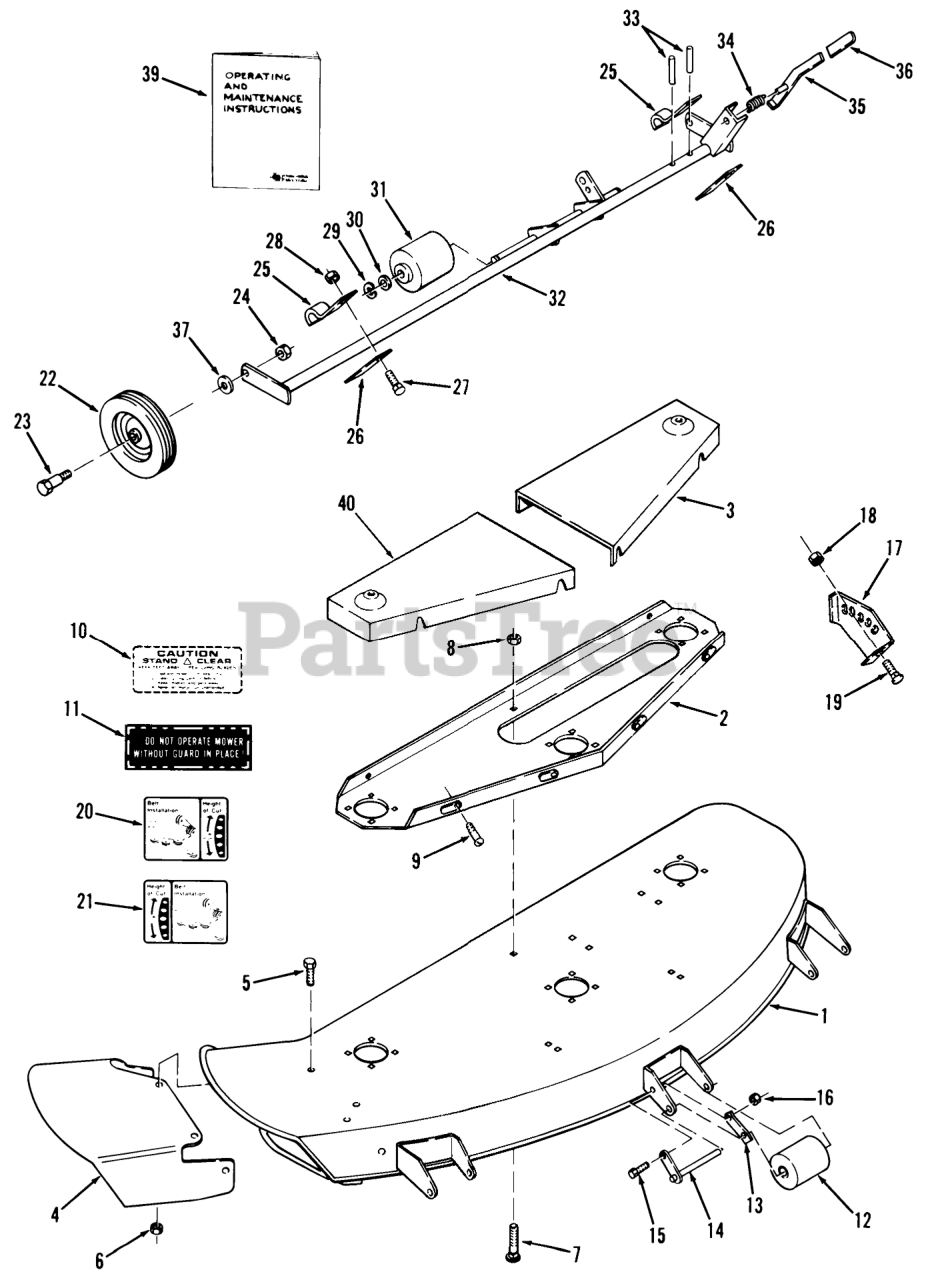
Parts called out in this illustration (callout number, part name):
1	ASSY DECK 42"MOWE R
1	ASSY-48 MOWER DEC R
2	Channel
3	Belt Cover LH
4	Chute Extension
5	Bolt
6	Nut
7	Bolt-Carriage
8	NUT
9	Bolt
9	Screw
10	Caution Decal
11	Decal-Caution
12	Roller
13	SPRING ROLLER STOP
14	Roller Shaft
15	H H C S
16	Nut
17	Quadrant
17	LH QUADRANT R
18	NUT
19	Bolt
20	DECAL-HEIGHT & BELT
21	DECAL-HEIGHT & BELT
22	Wheel 6 x 1.75 (w/5306 Bushings)
23	BOLT-SHOULDER
24	Nut
25	Machine Bolt
26	Bar
27	Bolt
28	NUT
29	E Ring
30	Washer
31	Roller
32	Support Ass-y. Gage Wheel
32	Gage Wheel Support
33	PIN-SPIROL
34	SPRING-COMPRESSION
35	LEVER ASSY R
35	Lever
37	WASHER
39	Operating and Maintenance Instructions
40	Belt Cover RH
